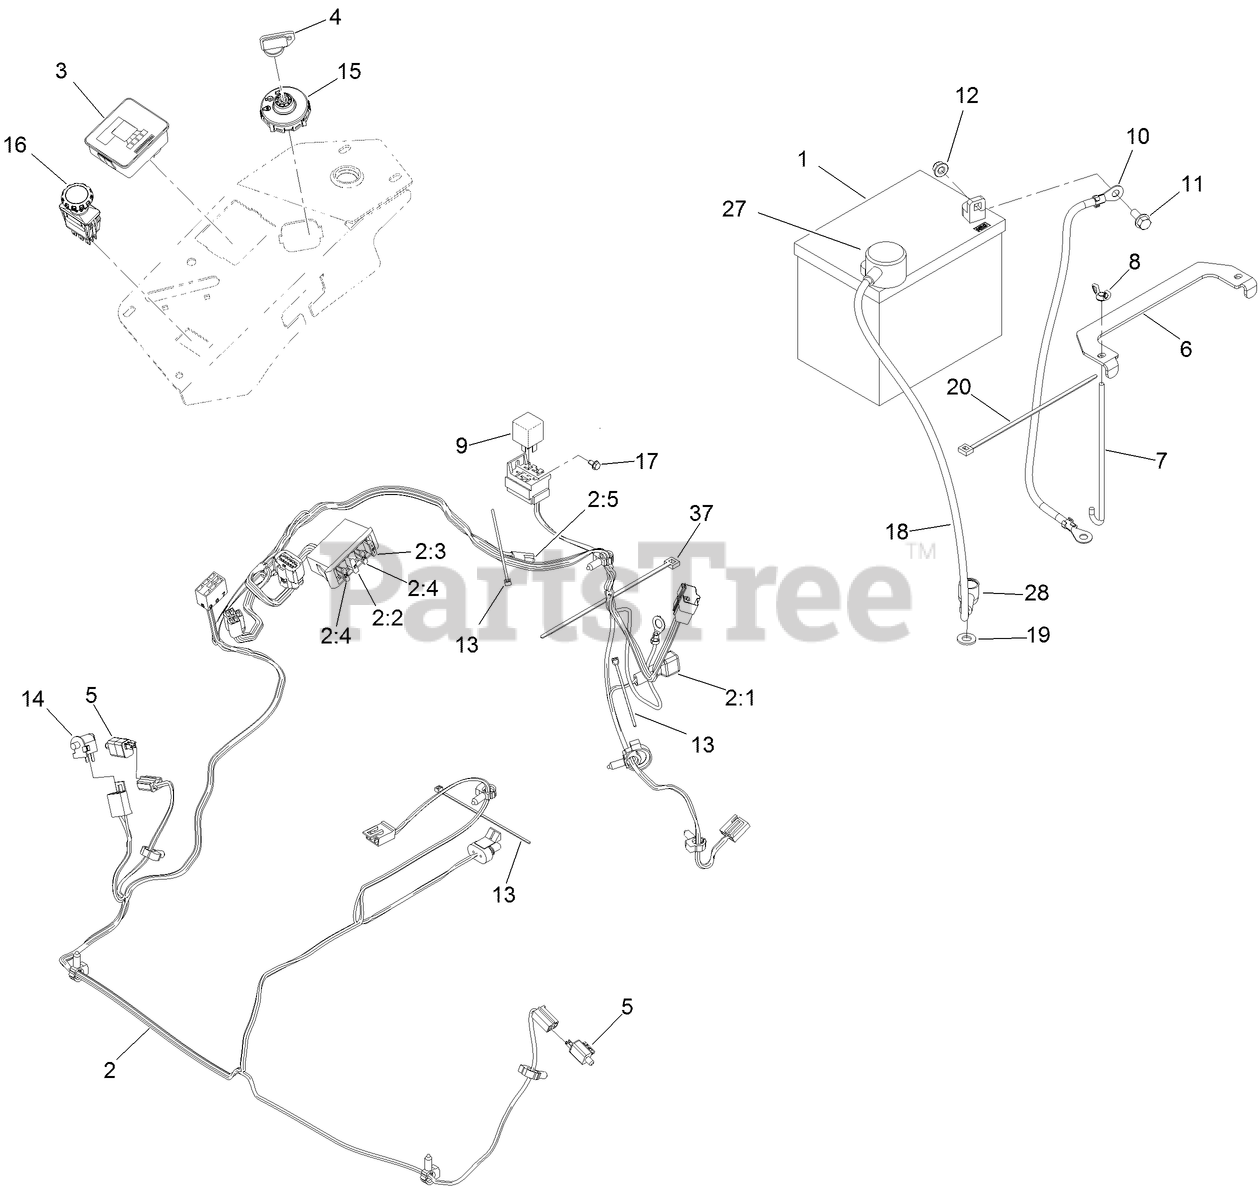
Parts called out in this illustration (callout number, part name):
1	BATTERY-DRY
2	HARNESS-WIRE, MAIN
2:2	FUSE-BLADE, 10 AMP
2:3	FUSE-BLADE, 15 AMP
2:4	FUSE-BLADE, 25 AMP
2:5	CAP-PLUG
3	FUEL/HOUR METER ASM
4	KEY-IGNITION
5	SWITCH
6	STRAP-TIE DOWN, BATTERY
7	BOLT-HOLDDOWN
8	WINGNUT
10	CABLE-BATTERY, NEGATIVE
11	SCREW-HHF
12	NUT-HF, NI
13	TIE-CABLE
14	SWITCH-BAIL
15	SWITCH-IGNITION
16	SWITCH-PTO, 10 AMP
17	SCREW-HWH
18	CABLE-BATTERY, POSITIVE
19	WASHER-FLAT
20	TIE-PLASTIC
27	INSULATOR-BATTERY
28	INSULATOR-SOLENOID
37	TIE-PLASTIC
